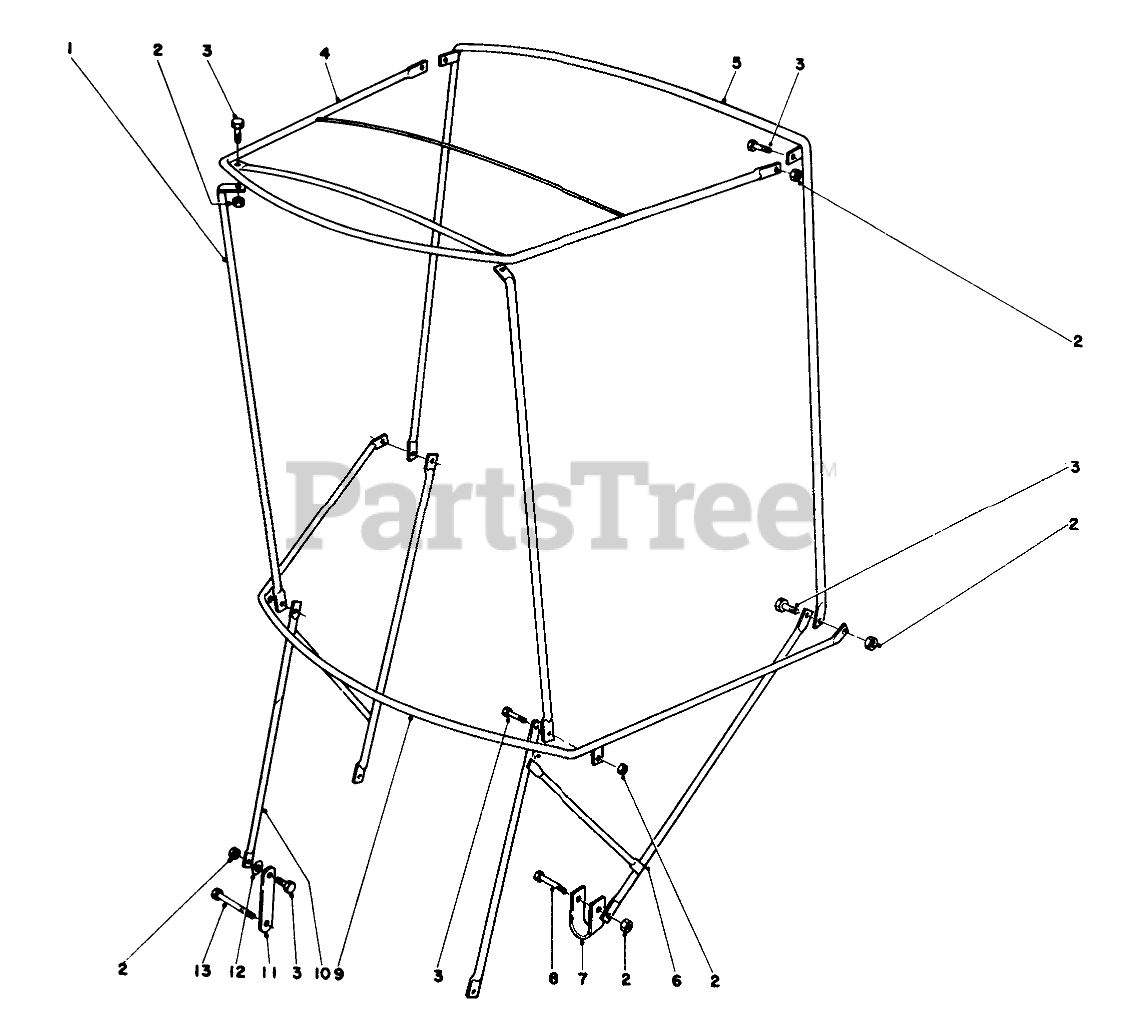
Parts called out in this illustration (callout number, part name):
2	NUT-LOCK
3	Bolt
4	FRAME-TOP
5	BOW-VERTICAL, REAR
6	Attaching Bracket, L.H.
7	U CLAMP
8	SCREW-HH
9	BOW-CURVED
10	Attaching Bracket, R.H.
11	Mounting Strap
12	WASHER-LOCK/EXT
13	SCREW-HH
